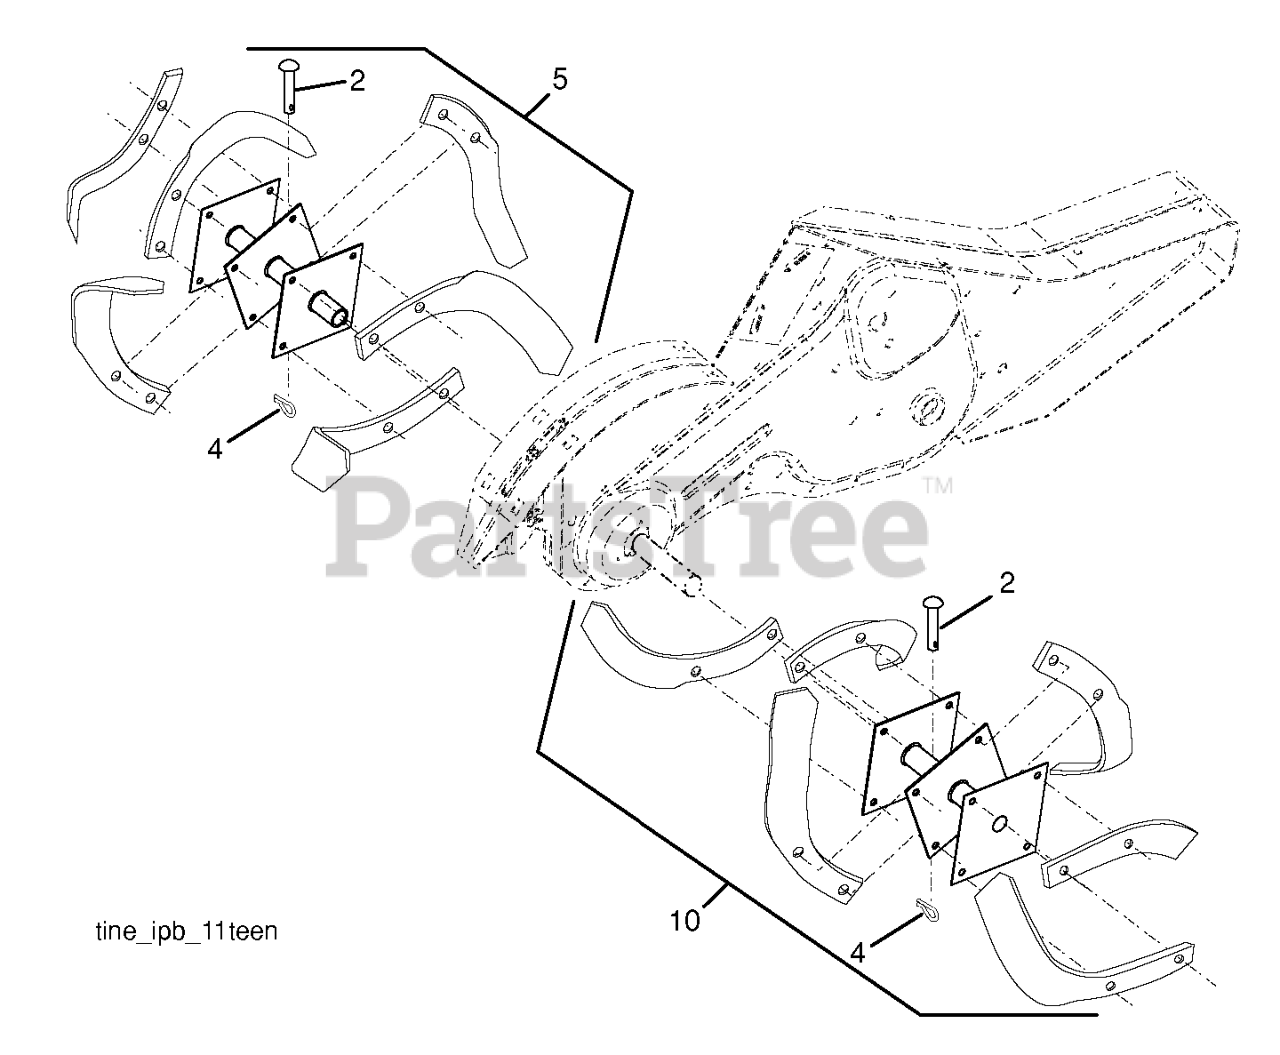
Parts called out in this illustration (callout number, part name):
2	PIN RETAINING SCREW
4	SPRING RETAINER
5	TINE.ASM.LH.TILLER.BLACK
10	TINE.ASM.RH.PNT.479
